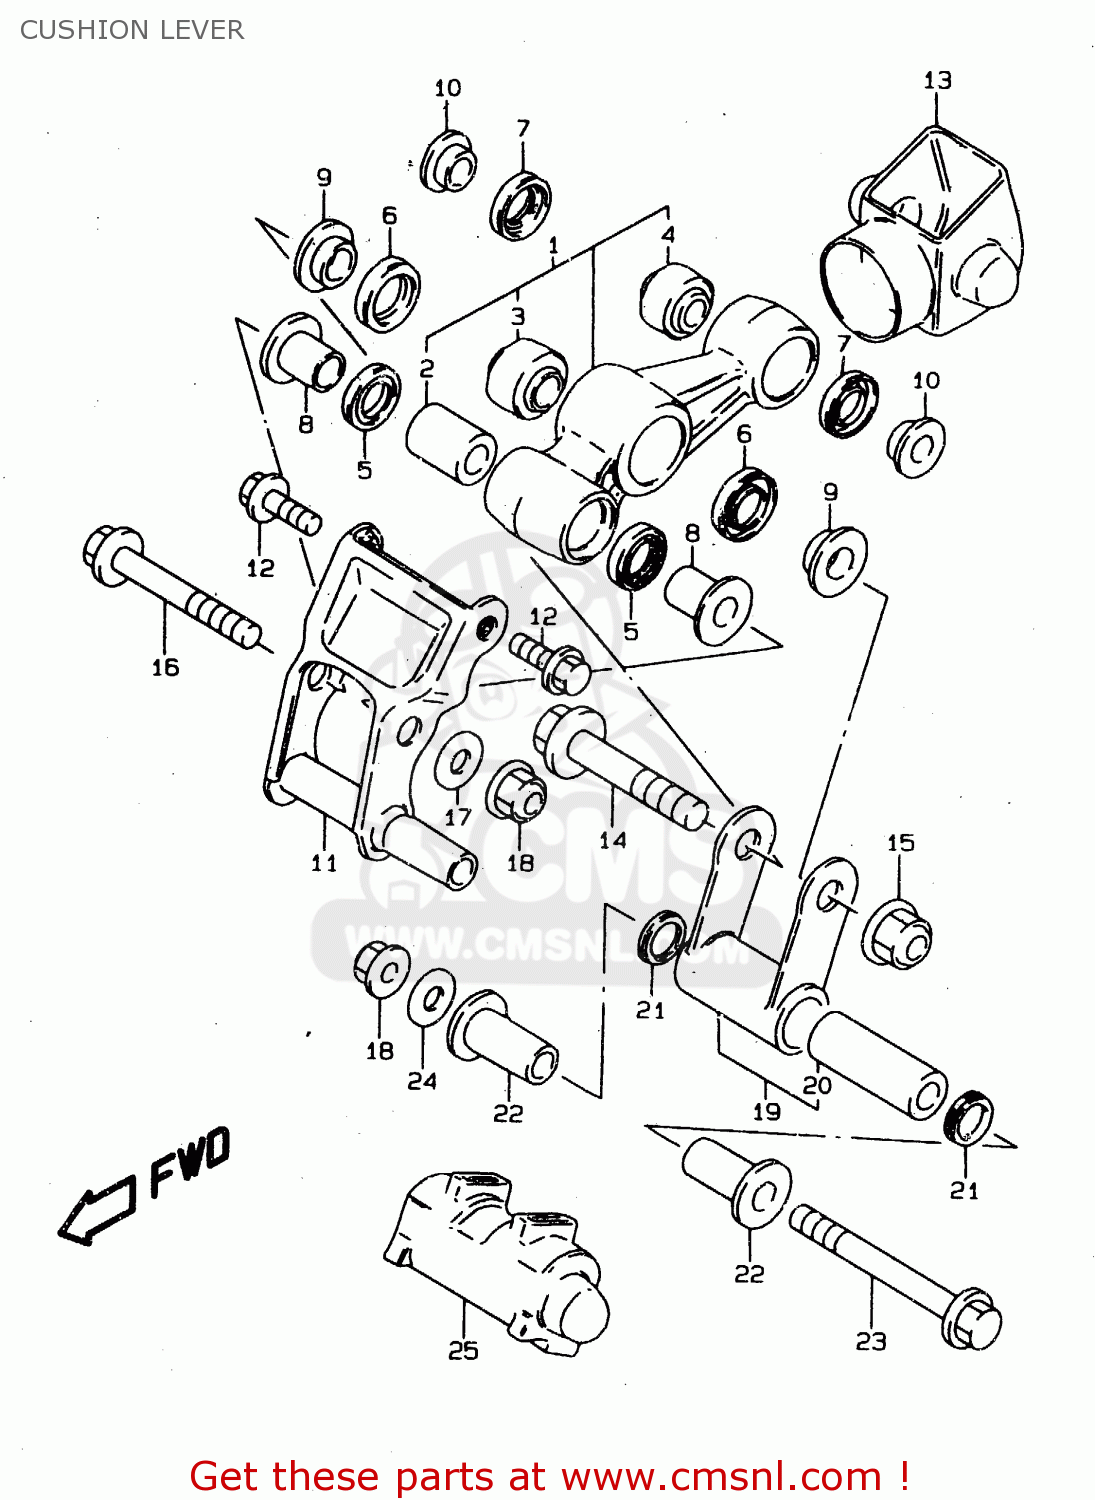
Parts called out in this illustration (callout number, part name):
1	LEVER SET,RR CUSHION
2	BUSHING,CUSHION FR(15X20X31)
3	BEARING(12X26X16)
4	BEARING(10X24X15)
5	DUST SEAL,RR CUSHION LEVER FR
6	DUST SEAL,RR CUSHION LEVER CTR
7	DUST SEAL,RR CUSHION LEVER RR
8	SPACER,RR CUSHION LEVER FR
9	SPACER
10	SPACER
11	HOLDER,RR CUSHION LEVER
12	BOLT,RR CUSHION LEVER HOLDER
13	BOOT,RR
14	BOLT(12X55)
15	NUT 12MM
16	BOLT(10X65)
17	WASHER(10.5X22X1.6)
18	NUT
19	LOD SET,RR CUSHION
20	BUSHING,LOD LWR(15X20X54)
21	DUST SEAL,LEVER CUSHION UNIT
22	SPACER,RR CUSHION ROD LWR
23	BOLT,RR CUSHION ROD LWR
24	WASHER(10.5X22X1.6)
25	BOOT,LWR
